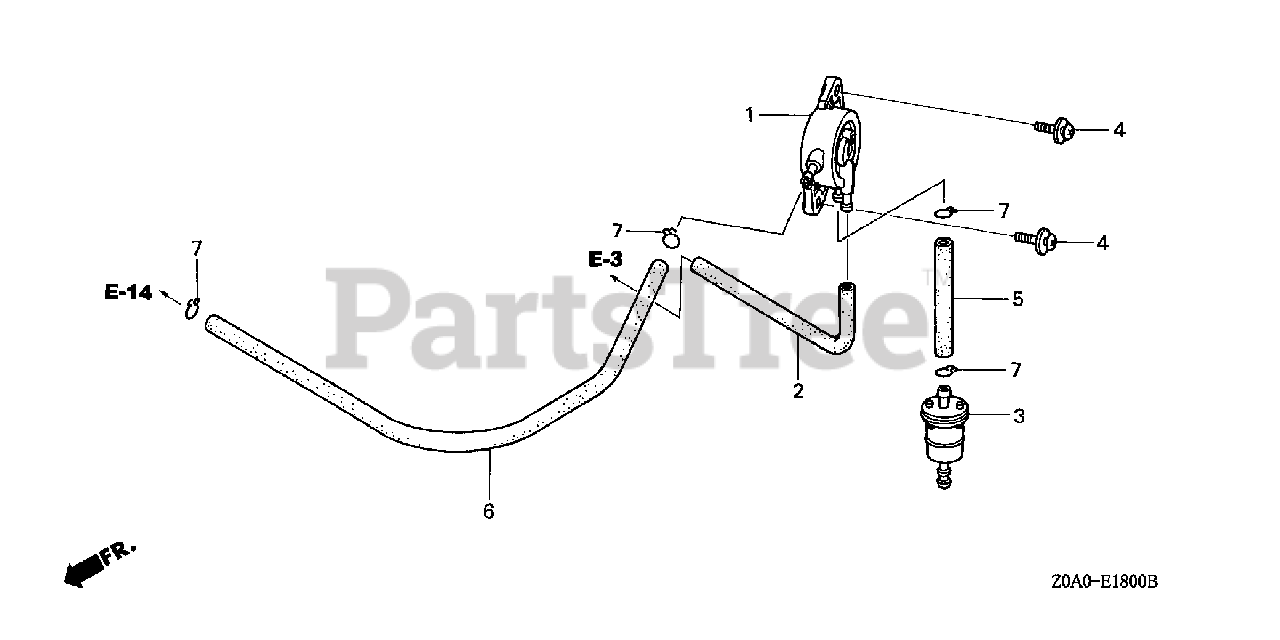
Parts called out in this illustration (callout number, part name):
3	FILTER, FUEL
5	BULK HOSE, FUEL (5.5X8000) (5.5X100)
7	CLIP, TUBE (B10)
